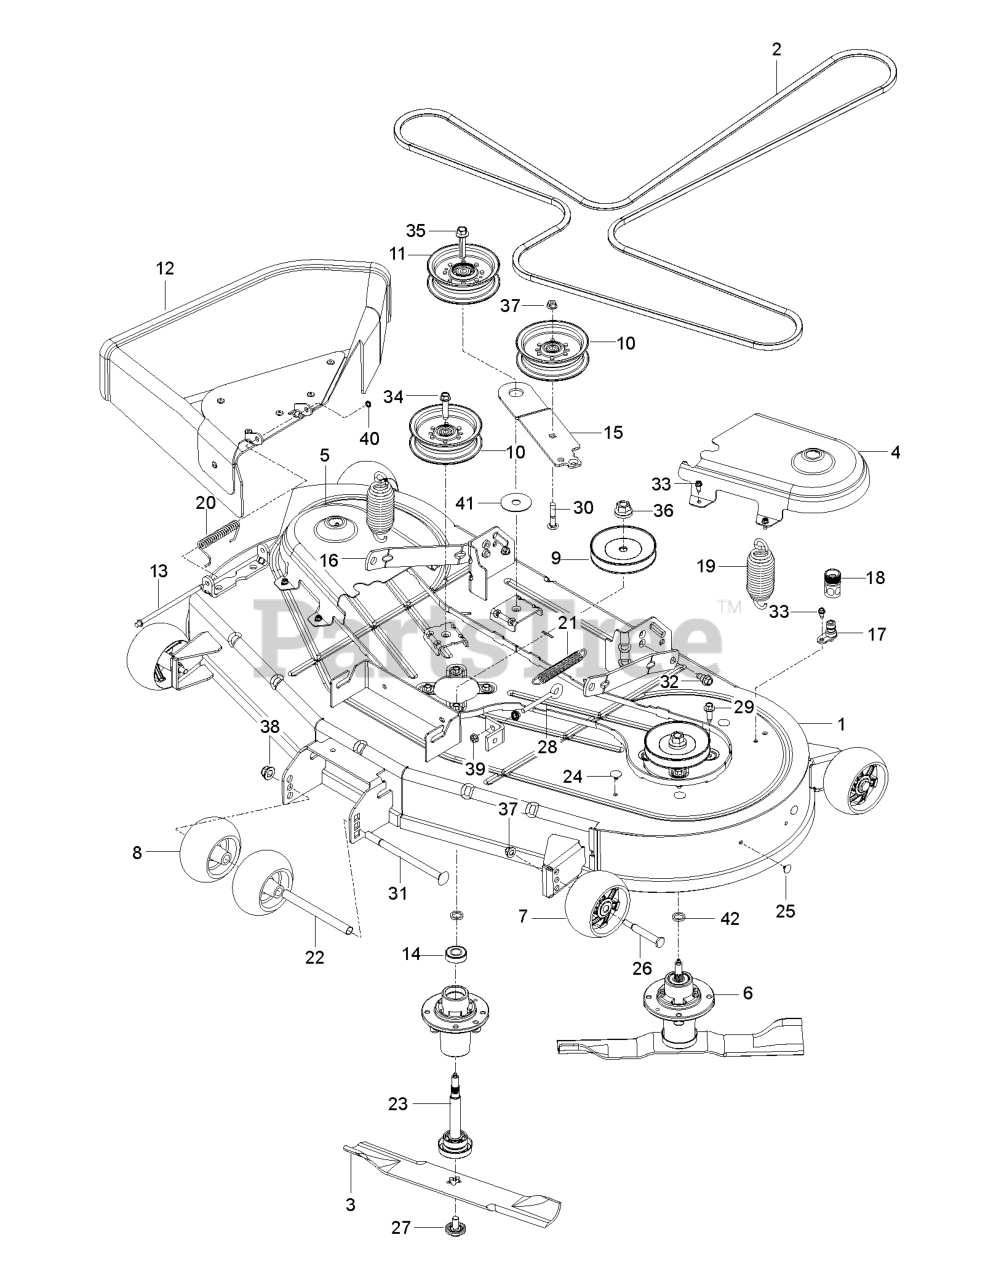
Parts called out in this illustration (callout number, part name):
2	BELT CLEARCUT 54, RZ DECK DRIV
3	BLADE CC54 PZ STYLE HI LIFT BL
4	COVER 54 CLEARCUT, LH MANDREL
5	COVER 54 CLEARCUT RH MANDREL B
6	MANDREL ASM, CAST IRON
7	WHEEL. GUAGE RALLY
8	ROLLER, GAUGE .635 BORN
9	PULLEY MANDREL
10	PULLEY.IDLER.2006
11	RB PULLEY.IDLER.4.50/HUB SPEC
12	DEFLECTOR ASSY 54 CLEARCUT RES
13	ROD.HINGE
15	ARM IDLER ARM, CLEARCUT 54 BLA
16	ARM.RFIXED.MOWER.SUSPNSIONX431
17	PORT.WASHOUT
18	COUPLING.QUICK CONNECT
19	SPRING
20	SPRING.42.FCS.DEFLECTOR
21	SPRING.EXTN.42.FCS.TR.DECK.DRV
22	TUBE, ROLLER AXLE LONG
23	SHAFT ASM MANDREL
24	PLUG CHRISTMAS TREE
25	FASTENER.XMAS.TREE
26	BOLT.SHOULDER.3/8-16X3-5/8.
27	BOLT.WASHER.ASM.7/16-2
28	EYE BOLT 5/16 X 3.50
29	BOLT.HEX.WASHR.HED.313-18X1.19
30	BOLT
31	RHSNB 1/2-13 X 8 GR5 ZD
32	BOLT.SHOULDER
33	SCREW.1/4-20X5/8
34	SCREW LT
35	SCREW.7/16-14 X 2.125.WASHER
36	NUT.FLANGE.LOCK.TOP
37	NUT LOCK FLG 3/8-16 UNC
38	NUT, 1/2-13 HEX FLG NYLOC ZD
39	NUT 5/16C WHIZ
40	NUT PUSH M
42	WASHER.SPACER.MANDREL
